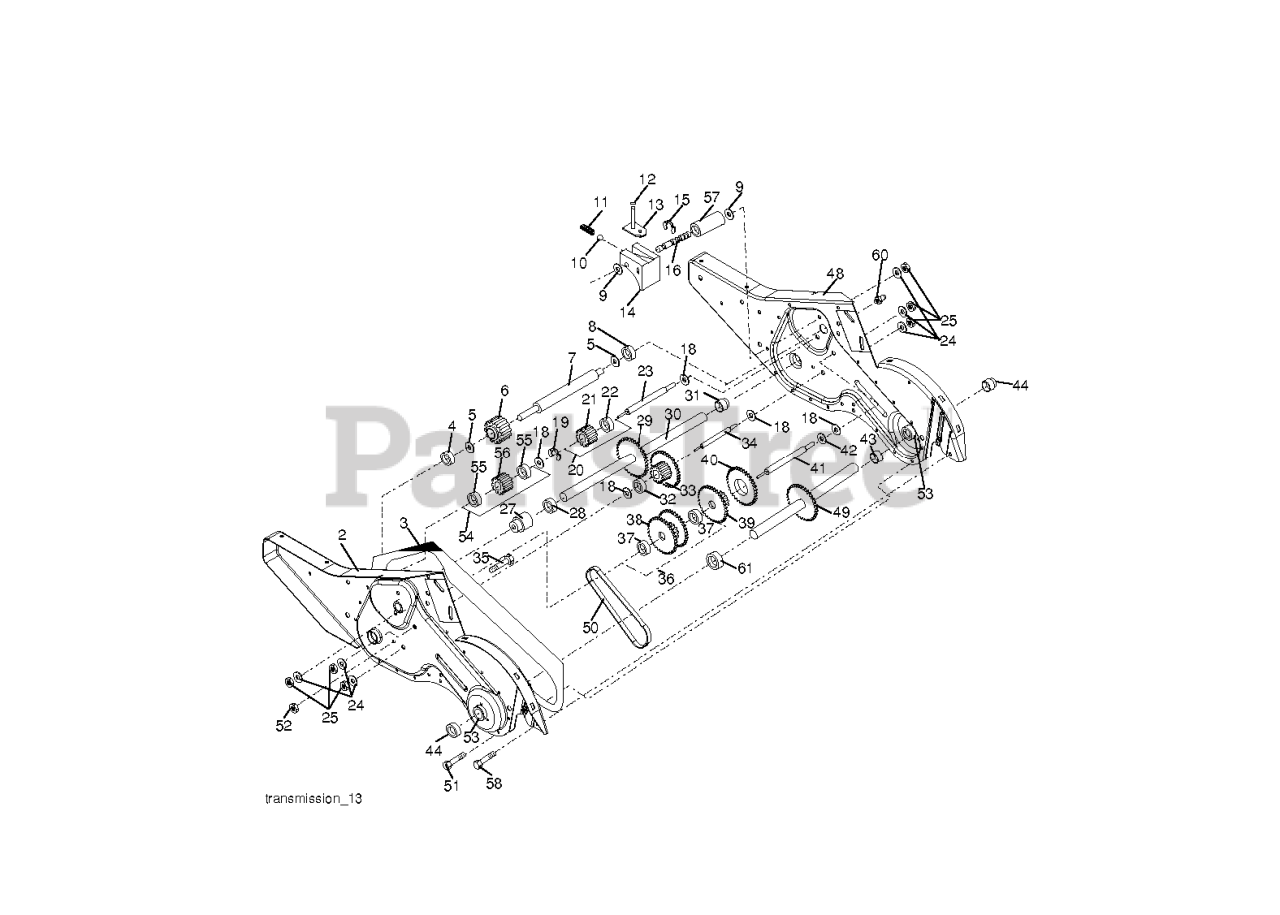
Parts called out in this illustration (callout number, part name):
1	TRANSMISSION.ASM.17
2	GEARCASE.ASM.DRT.LH.
3	GASKET.GEARCASE.CRT/DRT.TILLER
4	NEEDLE BRNG LT
5	THRUST WASHER
6	GEAR.PINION.INPUT.DRT
7	SHAFT.INPUT.D.9TEETH
9	WASHER, SEAL (2 2)
10	BALL, STEEL
11	SPRING-SHIFT CRT
13	BRACKET ASM.SHIFT.CRT
14	SHIFT FORK TI
16	SHAFT.SHIFT.DRT
20	GEAR ASSY CRT
21	GEAR-REV IDLR CRT
22	NEEDLE BEARING TI
23	SHAFT.IDLER.REVERSE.CRT
24	LOCKWASHER
25	NUT.ASF.HEX.7/16
27	BEARING, SHAFT LH CRT
30	GROUND SHAFT ASS'Y
31	BEARING, SHAFT RH CRT
33	SPRCKT 8 GEAR CRT
34	SHAFT.SECONDARY.REDUCTION.CRT
35	SCRW WHIZ LOK CRT
36	GEAR & SPROCKET.ASM.WBEARIN
37	BEARING.NEEDLE.CRT
38	ASM.GEAR & SPROCKET
39	GEAR.CLUSTER.DRT.TILLER
41	SHAFT.REDUCTION.FIRST.DRT
42	BRNG RACE T
44	SEAL ASM, OIL
48	GEARCASE.ASM.DRT.RH.
49	SHAFT.ASM.TINE
50	CHAIN.TILLER
51	SCREW
53	KIT.BEARING.TILLER.
54	GEAR.ASM.DRT.TILLER
55	BEARING.NEEDLE
56	GEAR.DRT.IDLER
57	SPACER.SPLIT
58	BOLT SHOULDER 1/4-20 UNC X.875
60	FITTING.GREASE.TAPERED
61	SPACER.1.015X1.50X.650
